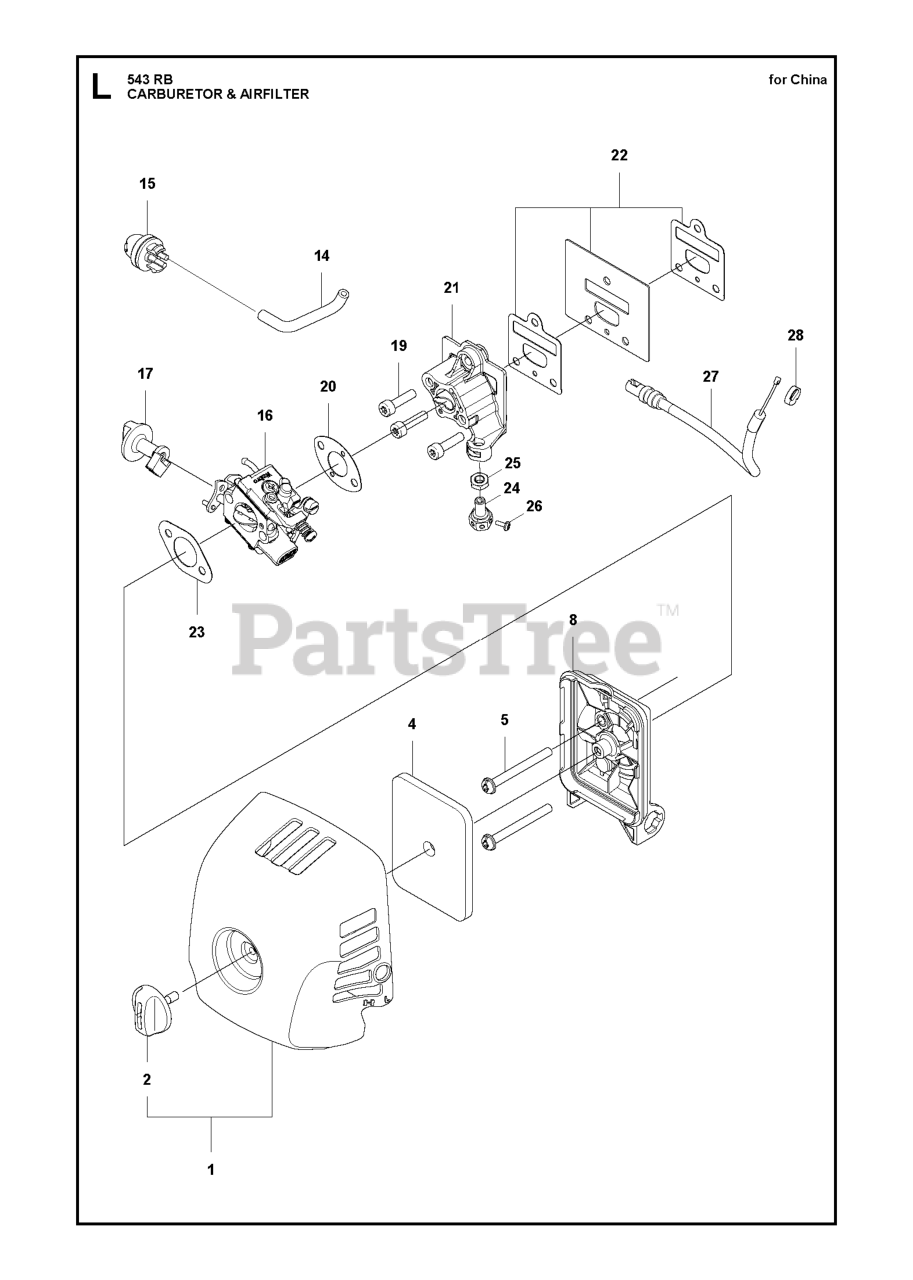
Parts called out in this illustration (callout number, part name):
2	TURNING KNOB GZ40N7
5	BOLT TORX
8	HOUSING
14	PIPE L70
15	AIR PURGE BUBBLE
17	KNOB
19	BOLT TORX
20	GASKET
21	INSULATOR
22	GASKET, INSULATOR
23	GASKET
25	NUT
26	SCREW
28	CAP
